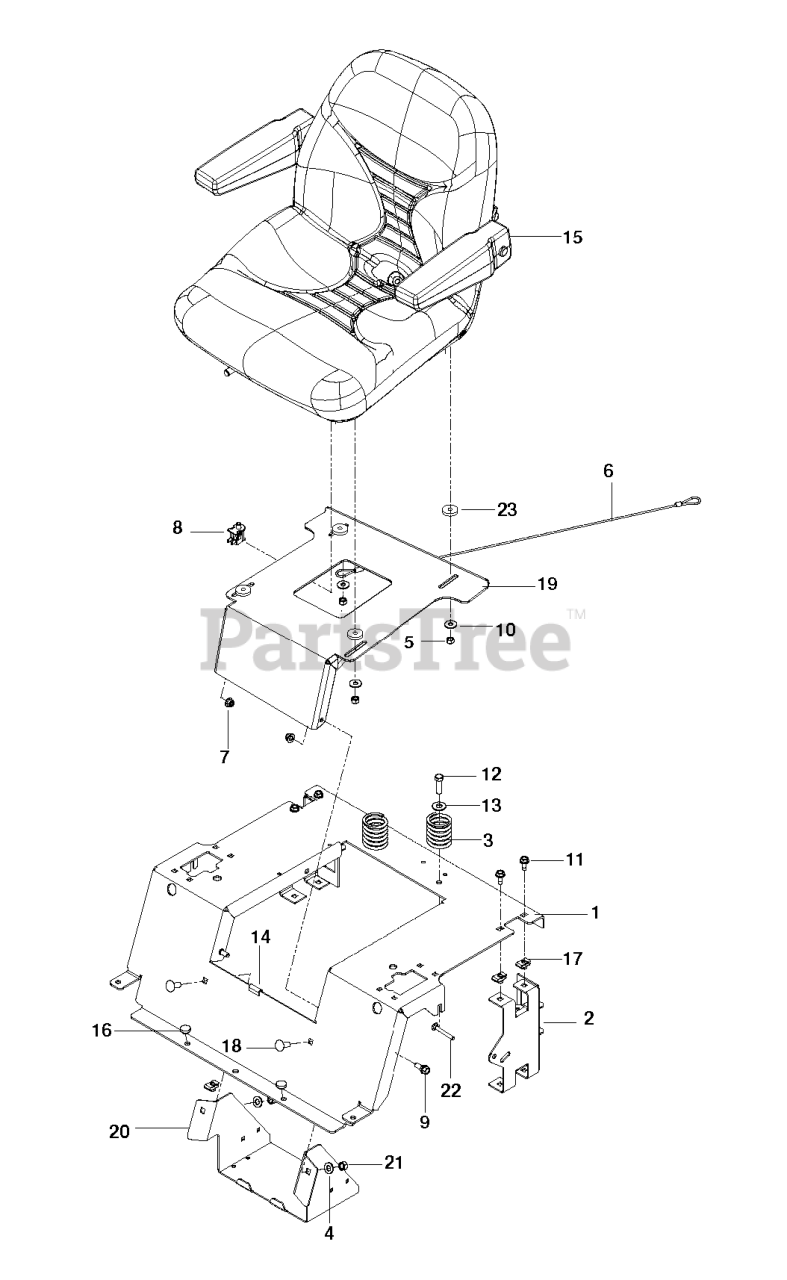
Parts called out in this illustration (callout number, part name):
1	SUPPORT, SEAT, FLAT ORANGE
2	SUPPORT, REAR SEAT, BLACK
3	SPRING, SEAT
4	WASHER 3/8 SAE FLAT
5	NUT 5/16 NYLOC
6	SEAT LANYARD
7	5/16-18 NYLOC FLANGE NUT
8	SEAT SWITCH
9	SB 5/16-18 HEX HD GD5, BLK ZN
10	WASHER 5/16 FLAT
11	BOLT 5/16-18 X 3/4
12	HCS 3/8C X 1 1/4 GR5
13	WASHER 3/8 FLAT
15	SEAT
16	GROMMET, BUMPER
17	U-CLIP 5/16-18 NUT RETAINER
18	RHSNB 3/8C X 1
19	PAN, SEAT, ORG
20	BOX, BATTERY, BLACK
21	NUT 3/8-16 NYLOC
22	RHSNB 5/16-18 X 2-1/2 GR5 ZD
23	WASHER NYLON
